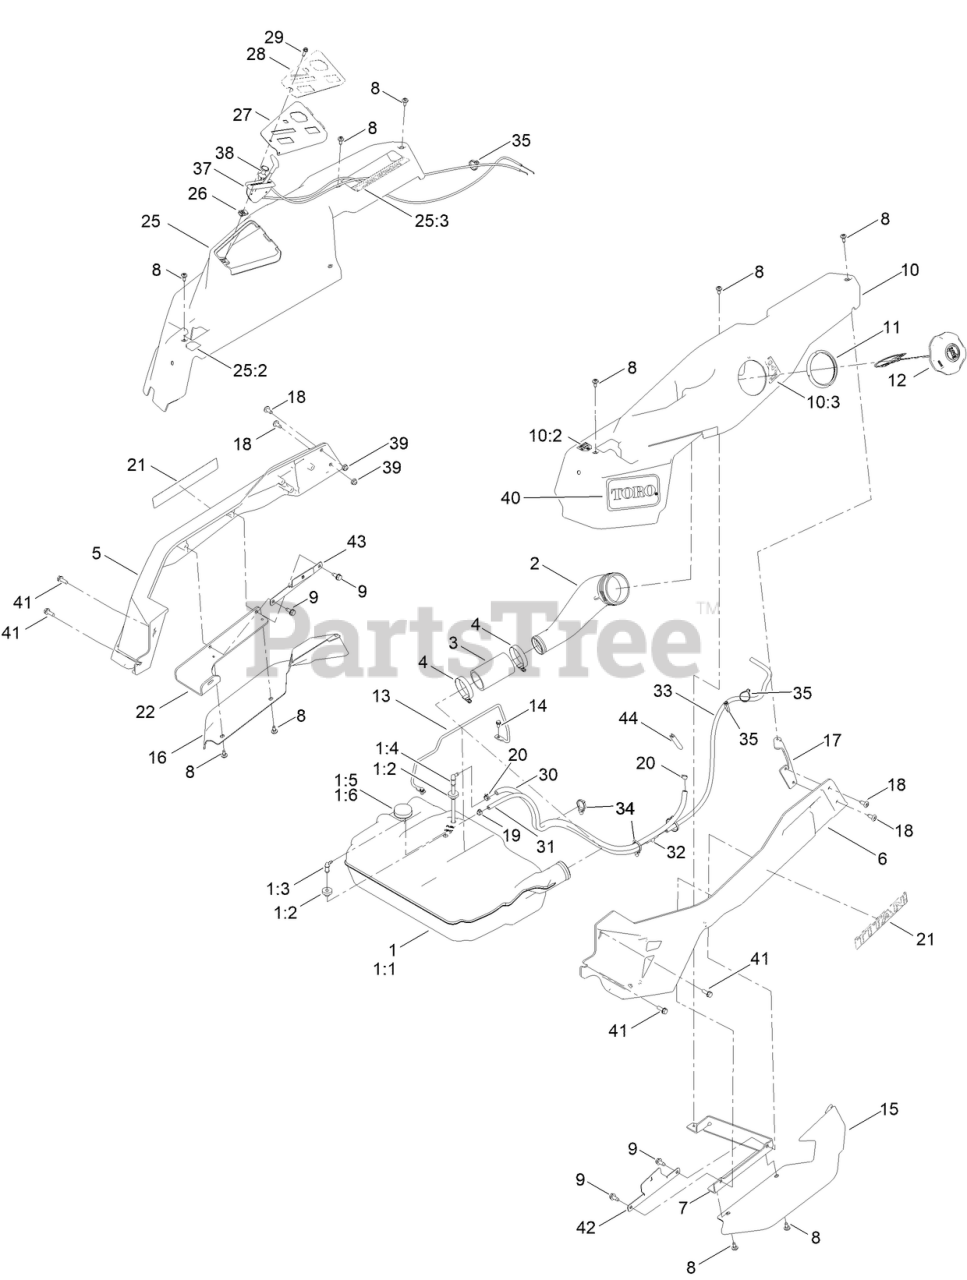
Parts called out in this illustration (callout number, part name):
1	TANK-FUEL, ASM
1:1	TANK-FUEL
1:2	BUSHING
1:3	FITTING-ELBOW 90
1:4	FITTING - PICKUP, FUEL
1:5	GROMMET-FUEL
1:6	REMOTE GAUGE ASM
2	NECK-FILLER, FUEL
3	HOSE-FILLER, FUEL
4	CLAMP-HOSE
5	CAST-TUBE, RH [RED]
6	CAST-TUBE, LH [RED]
7	MOUNT-POD BRACKET LH
8	SCREW-SHOULDER
9	SCREW-HWHTF
10	POD ASM - LH W/DECALS
10:2	DECAL-CONTROL LEVER, LH
10:3	DECAL-FUEL FILL
11	RING-RETAINING
12	CAP-FUEL, RATCHETING
13	ROD-HOLD DOWN
14	SCREW-HWH
15	FENDER-TIME CUTTER, LH
16	FENDER-TIME CUTTER, RH
17	BRACKET-REAR POD, LH
19	CLAMP-HOSE
20	CLAMP-HOSE
21	DECAL-TITAN
22	BRACKET-MR SPRING
25	POD ASM - RH , MR W/DECALS
25:2	DECAL-CONTROL LEVER, RH
25:3	DECAL - MYRIDE
27	PANEL-CONTROL
28	DECAL - CONTROL PANEL
29	SCREW-HWHTF
30	HOSE-FUEL
31	HOSE-FUEL
32	ADAPTER ORIFICE
33	HOSE-LP
34	CLIP-TIE
35	TIE-CABLE
37	CABLE-THROTTLE
38	CABLE-CHOKE
39	NUT-HF
40	DECAL - TORO LOGO
41	SCREW-TAPTITE
42	BRACKET-ALIGNMENT, POD LH
43	BRACKET- ALIGNMENT, POD RH MR
44	TRIM-EDGE GUARD
